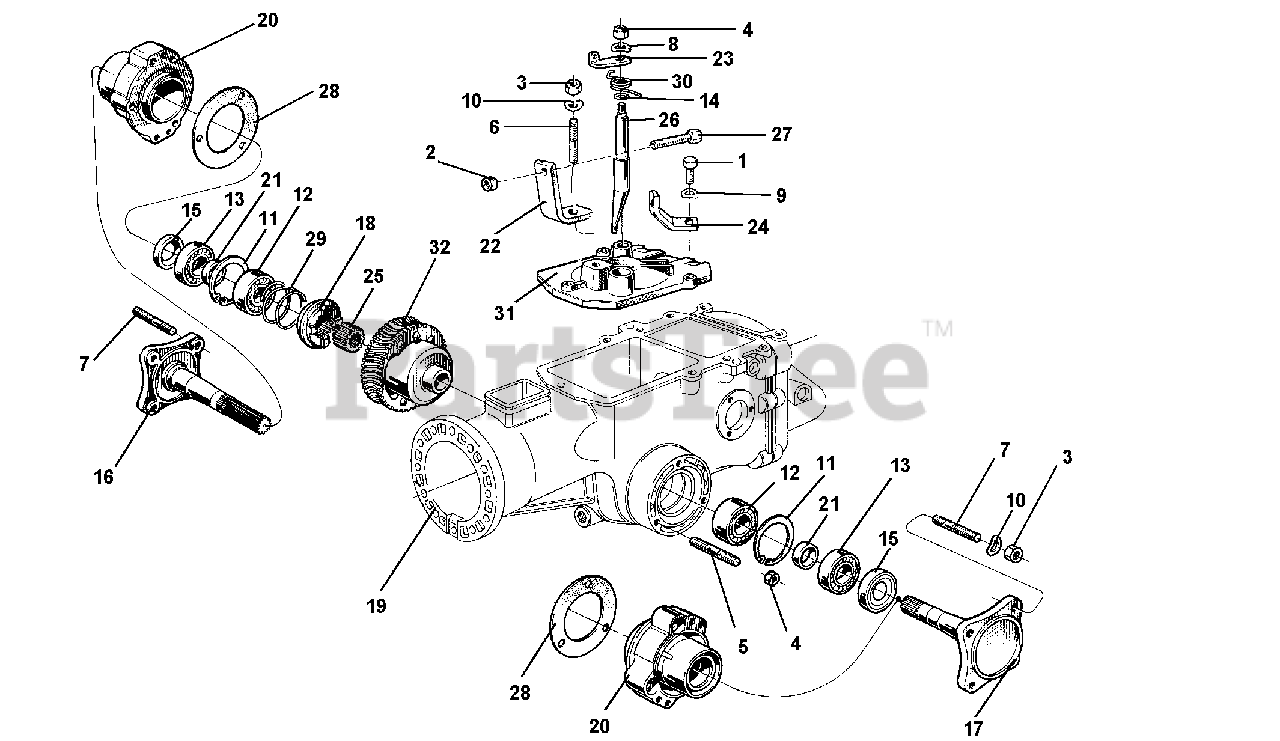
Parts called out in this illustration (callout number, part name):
1	SCREW TE M8 X 30
4	NUT, SELF LOCKING M8
5	STUD M8 X 46 X 20 X 12
6	STUD M10 X 37 X 19 X 15 8G
7	STUD M10 X 40 X 22 X 14
8	WASHER, FLAT 8.4
9	WASHER, LOCK 8.4
10	WASHER, LOCK 10.5
11	CIRCLIP, INTERN. D 47
12	BEARING 20 X 52 X 15 6304
13	BEARING 25 X 47 X 12
14	O-RING 2056 14.00 X 1.78
15	SEAL, OIL 30 X 40 X 7 STANDARD
16	HALF AXLE RIGHT LONG
17	HALF AXLE LEFT SHORT
19	CASING 5 SPEEDS GEARBOX
20	HUB FOR HALF-AXLE
21	RING FOR HALF AXLE
22	BRACKET CLUTCH CONTRAST
23	LEVER RELEASE
24	CONTRAST DIFFERENTIAL SHEATH
25	SPACER FOR DIFFERENTIAL
27	SCREW, ADJUSTING M8
28	JOINT GASKET
31	COVER DIFFERENTIAL
32	LEFT DIFFERENTIAL
